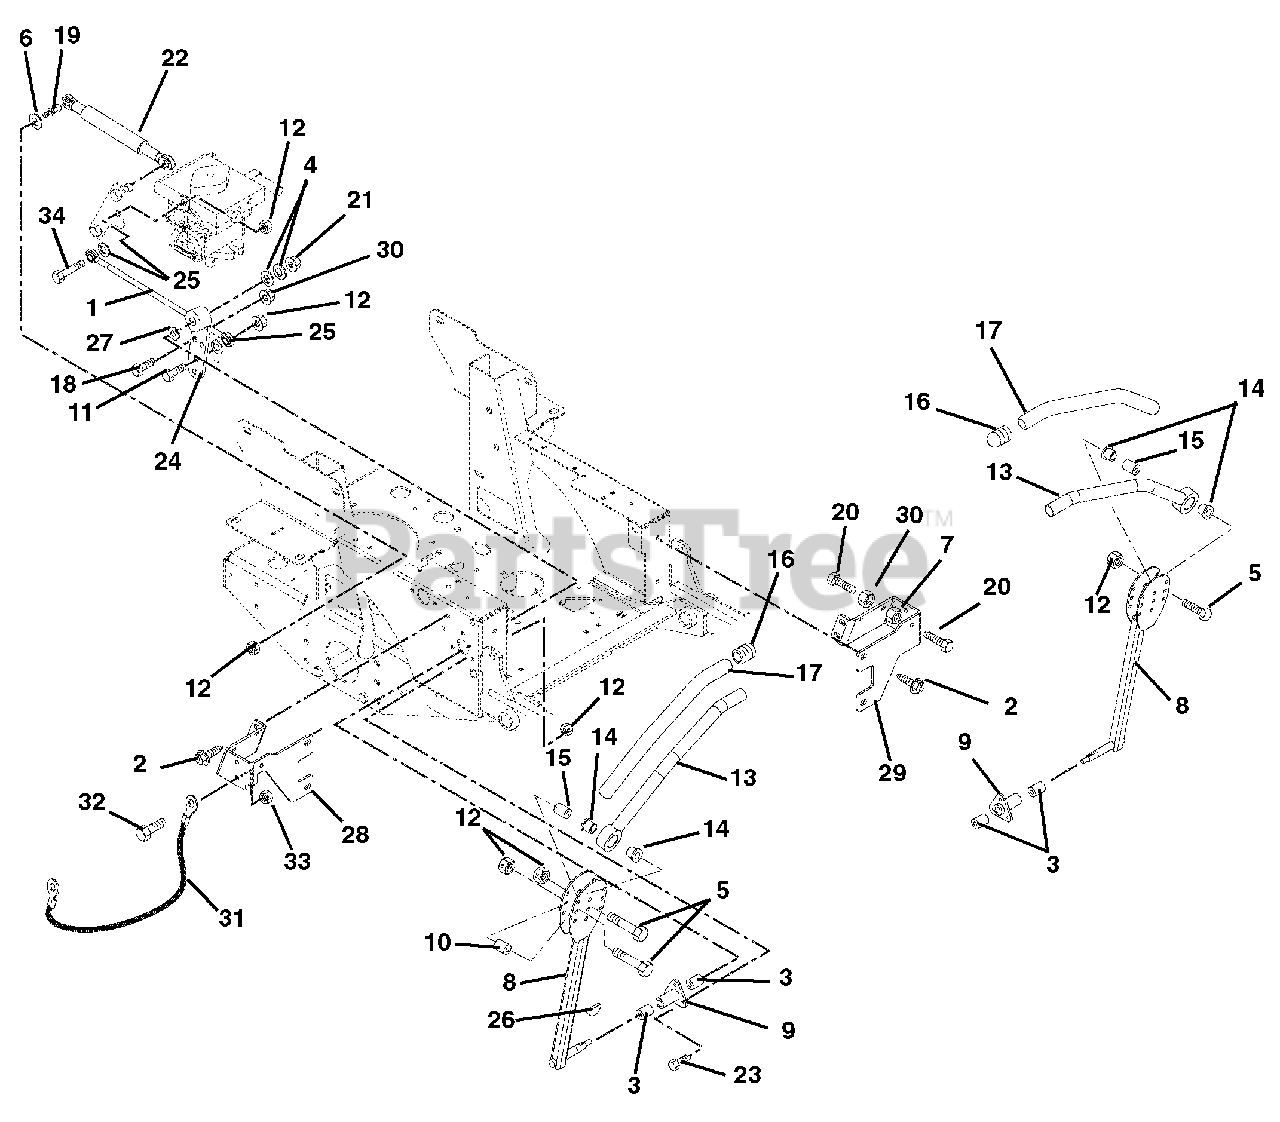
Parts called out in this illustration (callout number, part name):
1	ASSY, STEERING ROD
2	@SCR-TAP .38-16X.75 HWH TR YWZ
3	BSHG .625X.750X.500
4	@WSHR-FL-STL.406X.812X.065 YWZ
5	@BLT-HEX .31-18X1.75 GR5 YWZC
6	@WSHR-FL-STL.344X.688X.065YWZC
7	NUT-HEX-JAM .375-16 YWZC
8	CONTROL ARM - BLACK
9	BUSHING, FLANGE
10	BSHG,ECCEN .328X.750X1.01 PM
11	@BLT-HEX .31-18X1.25 GR5 YWZC
12	@NUT-LK-NYL-FLG .31-18 YWZC
13	HANDLE WLDMT LH
14	BSHG-FLG .762X1.48X.44 NYL
15	SPACER .328 X .76 X 1.01
16	CAPLUG - HANDLEBAR
17	GRIP - HANDLEBAR
18	BLT-HEX .375-16X1.750 FTD YWZC
19	STUD- BALL
20	@BLT-HEX .38-16X1.25 GR5 YWZC
21	@NUT-LK-NYL-FLG .38-16 YWZC
22	DAMPENER, CONTROL
23	@BLT-HEX .31-18X1.00 GR5 YWZC
24	ARM, PIVOT
25	@WSHR-LK .31X.078 REG YWZC
26	KEY-WDRF .13X.63 HRD#5
27	WAVE WASHER .640X.875X.125FH
28	STOP, STEERING-RH (BLACK)
29	STOP, STEERING -LH (BLACK)
30	@NUT-LK-CTR-JAM .375-16 YWZC
31	CBL,HOOD
32	@BLT-HEX .25-20X.75 GR5 YWZC
33	@NUT-LK-NYL-FLG .25-20 YWZC
34	@BLT-HEX .31-18X1.50 GR5 YWZC
